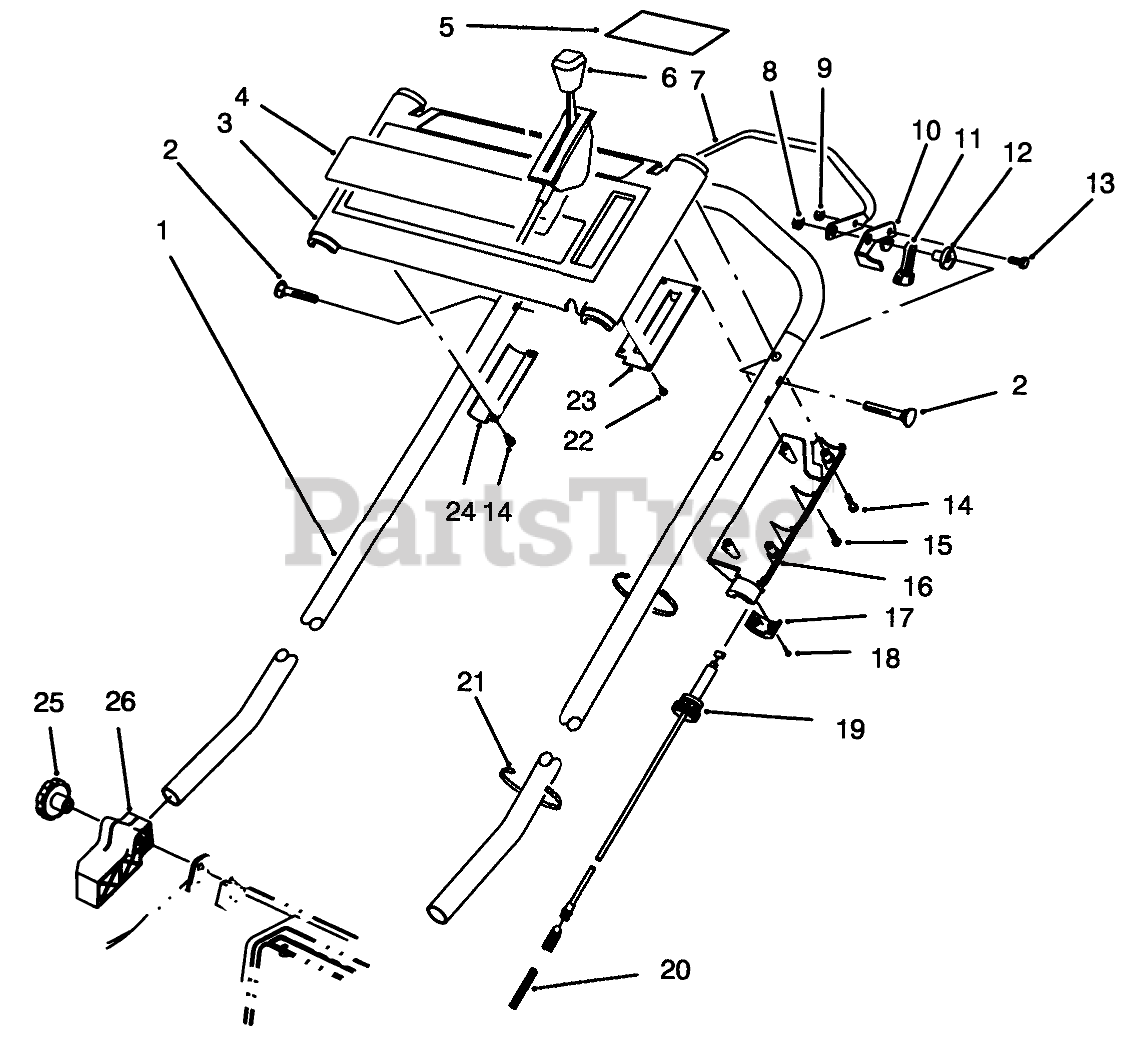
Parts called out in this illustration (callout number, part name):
1	HANDLE (DIPPED)
2	SCREW-HANDLE
3	Panel-Control (Incl. Ref. #4, & 5)
4	DECAL - PANEL OHV
5	DECAL - PANEL
6	THROTTLE CONTROL
7	CONTROL BAR
8	NUT-LOCK, NI
9	NUT-LOCK, NI
10	LEVER-CONTROL
11	LEVER-TRACTION
12	SPACER-SUPPORT
13	SCREW-HH
14	SCREW-PPH, PLASTITE
15	Screw
16	Cover-Throttle Lower
17	LOWER THROTTLE CAP
18	#4-14X.62 PLASTITE SCW
19	TRACTION CABLE
20	SPRING-COMPRESSION
21	TIE-CABLE
22	#6-19X.25 PLASK FORM SC
23	THROTTLE PLATE
24	Bracket-Panel
26	MOUNT-HANDLE, RH
